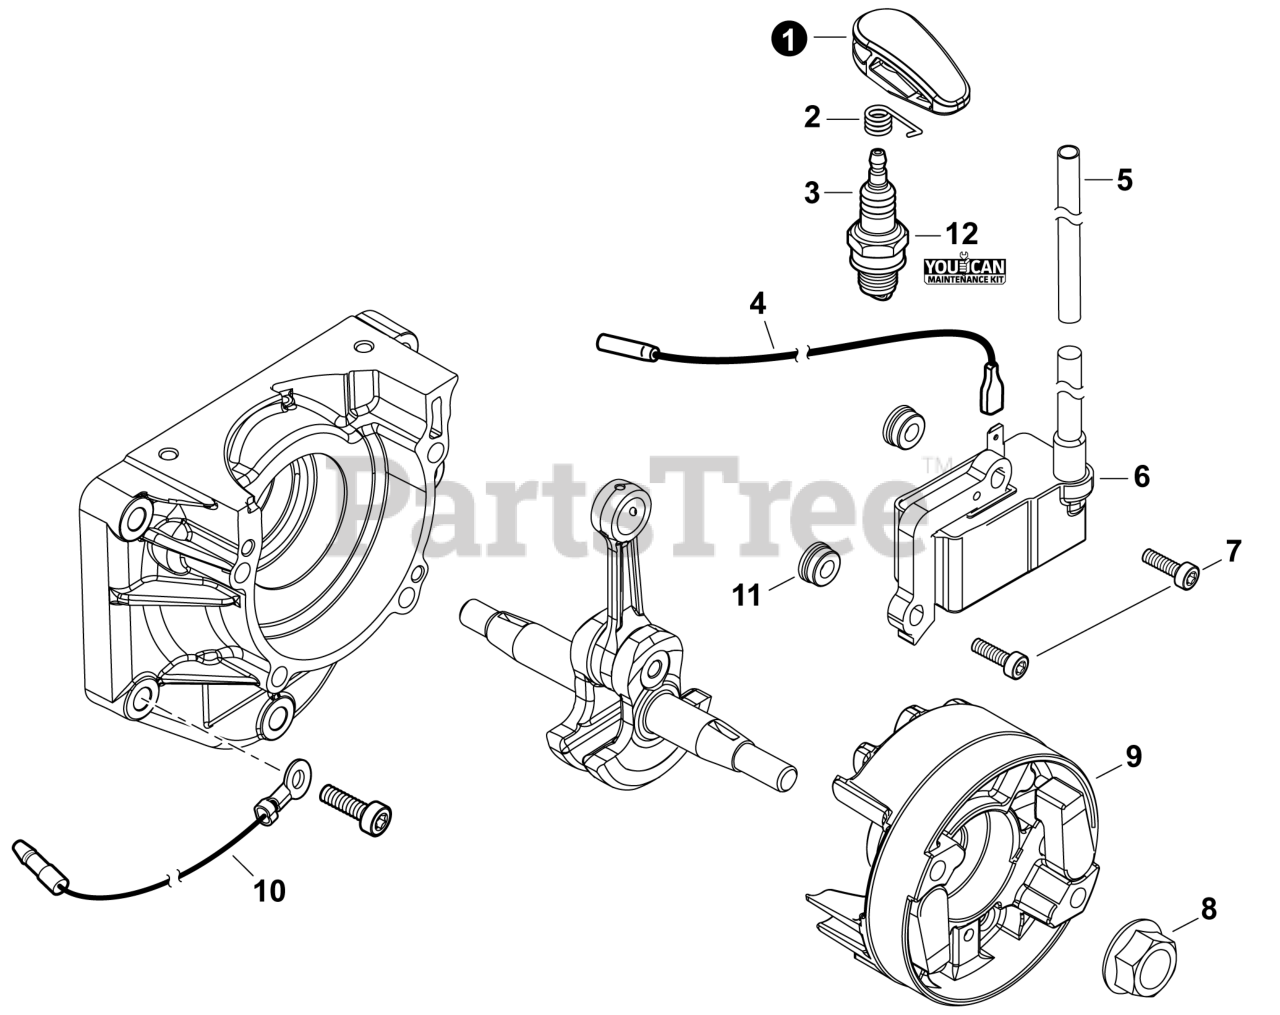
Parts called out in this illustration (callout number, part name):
1	CAP, SPARK PLUG
2	TERMINAL, SPARK PLUG
3	SPARK PLUG - CMR7H
5	TUBE, INSULATOR
6	COIL, IGNITION
7	BOLT 4x20
8	NUT, FLANGE 10x1.25
9	FLYWHEEL
11	COLLAR 4
12	TUNE-UP KIT - YOUCAN?
